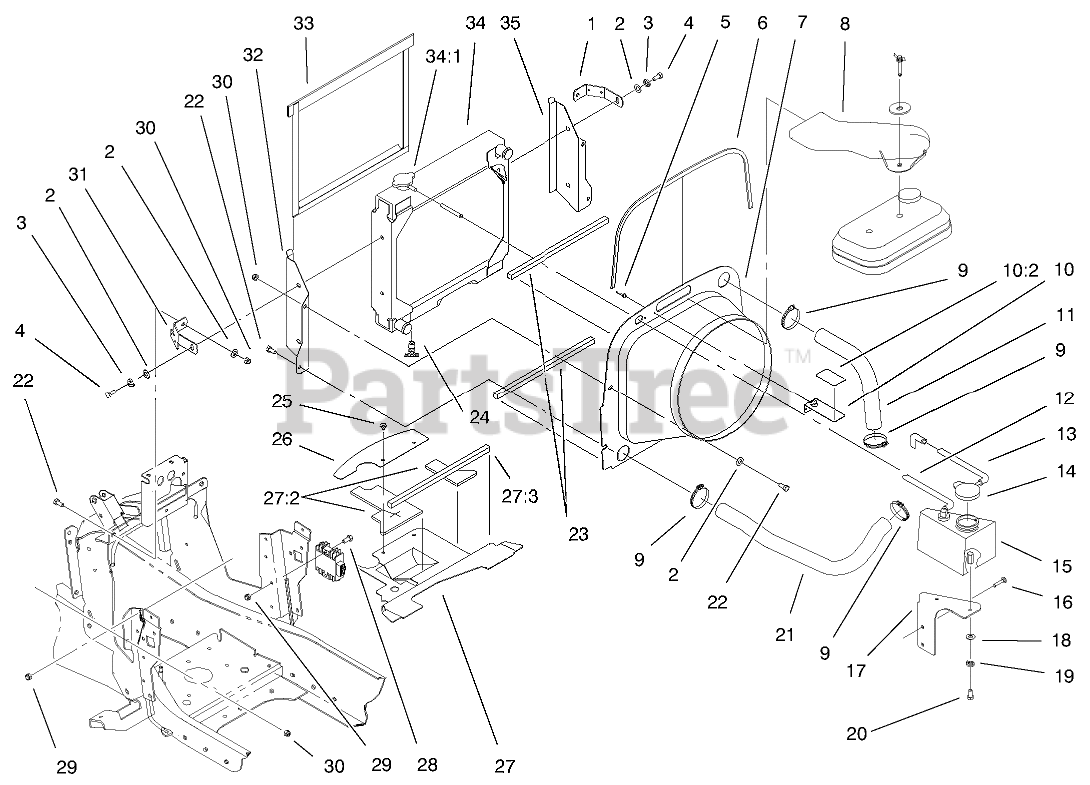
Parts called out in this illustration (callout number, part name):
2	WASHER-PLAIN
3	WASHER-LOCK
4	SCREW-HH
5	RIVET-POP
6	TRIM - LOC 31"
7	SHROUD - FAN
8	DUCT - AIR, KAWASAKI
9	CLAMP-HOSE
10	FAN/DECAL ASM
10:2	DECAL - WARNING
11	HOSE - RAD. KAWASKI
12	HOSE - FUEL LINE
13	HOSE - OVERFLOW
14	CAP - COOLANT RESERVOIR
15	BOTTLE - OVERFLOW
16	BOLT-CARR
17	Brkt-Bottle
18	WASHER-FLAT
19	WASHER-LOCK
20	SCREW-HH
21	HOSE - RAD. KAWASKI
22	SCREW-HH
23	FOAM - RADIATOR/SHROUD
24	VALVE - DRAIN
25	RIVET - PLASTIC
26	BAFFLE - TOWER REAR
27	BAFFLE-TOWER ASM
27:2	FOAM - BAFFLE
27:3	FOAM - RADIATOR/SHROUD
28	SCREW-HH
29	NUT-HEX
30	NUT-LOCK, NI
31	Bracket-Relay
32	Support-Radiator RH
33	SCREEN - CHAFF
34	RADIATOR - GAS
34:1	CAP-RADIATOR
35	Support-LH Radiator
